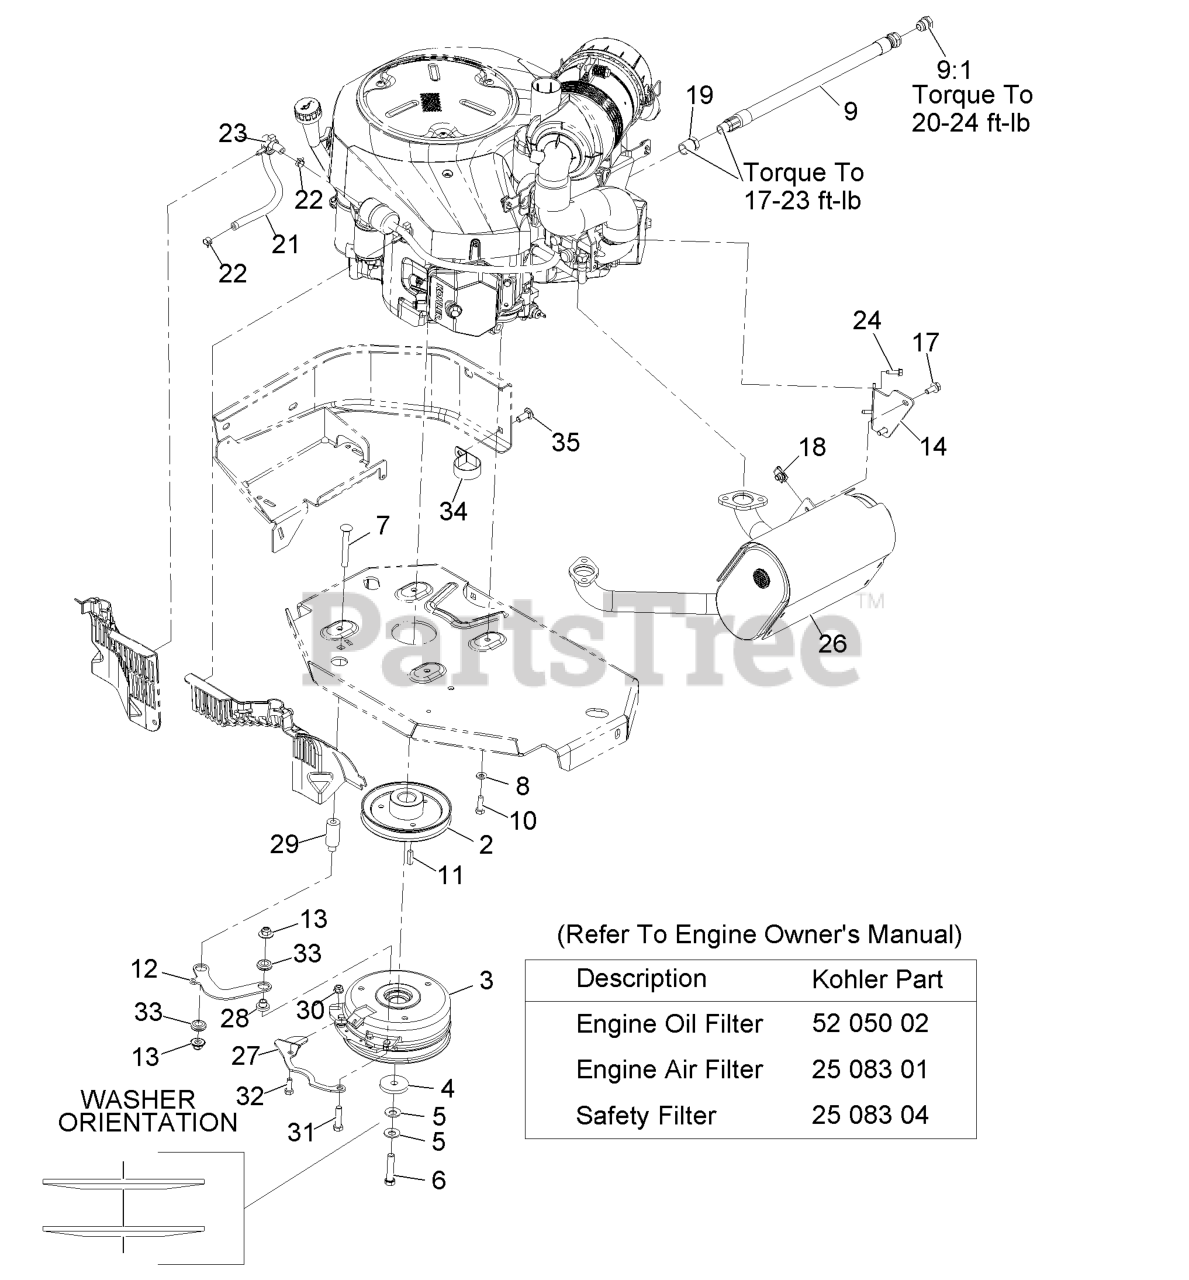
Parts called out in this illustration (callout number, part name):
2	SHEAVE
4	WASHER-CLUTCH
5	WASHER-SPRING
6	SCREW-HH W/LOCTITE
7	SCREW-CARR
8	WASHER-SPRING
10	SCREW-HH
12	LINK-ANCHOR, CLUTCH
13	Nut-Nyloc 3/8-16 Flg
17	SCREW-HHF
19	BUSHING
22	CLAMP-HOSE
23	CLAMP-HOSE
26	MUFFLER
27	BELT-GUIDE
30	NUT-HF, NI
31	SCREW-HH
32	SCREW-HH
33	GROMMET-RUBBER
34	CLAMP-R
35	SCREW-CARR
